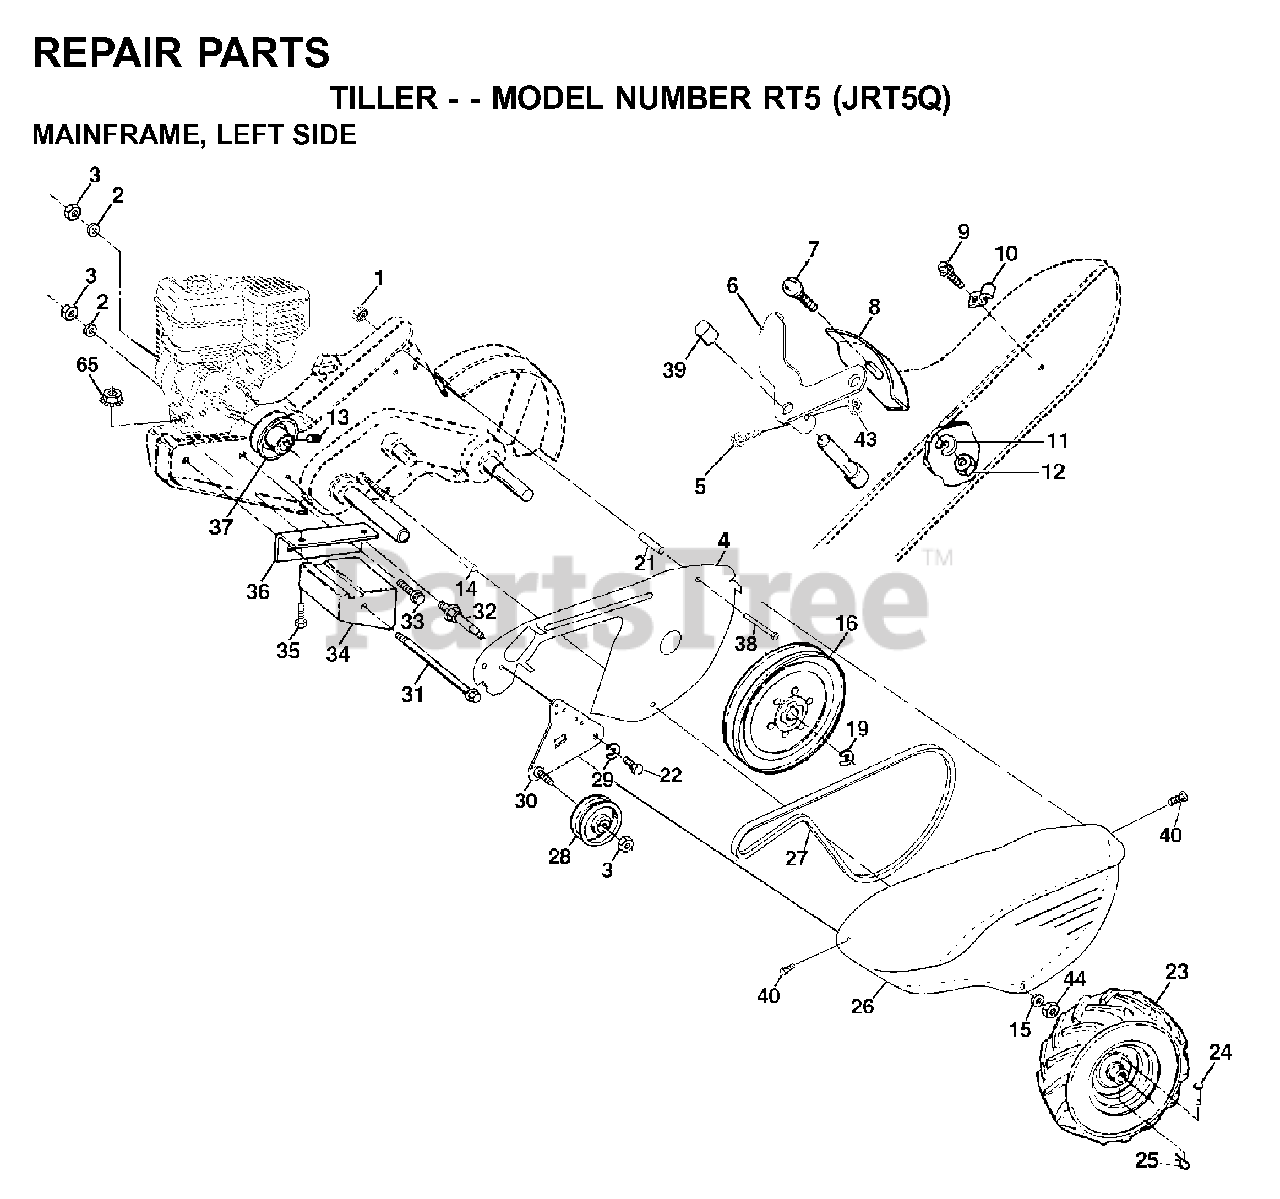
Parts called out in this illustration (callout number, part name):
1	NUT
2	WASHER, LOCK 3/8
3	NUT.HEX.3/8-16UNC
5	SCREW, SHIFT LEVER
6	LEVER ASM CRT
9	TAPPING SCREW
10	CONDUIT CLIP T
11	LOCKWASHER
12	NUT
13	SET SCREW **
14	SPACER-SPLIT.327 X .42
15	WASHER
16	SHEAVE, TRANSMISSION
19	RETAINING RING LT
21	SPACER CRT
24	RIVET,DRILLED
25	RETAINER M
27	V-BELT
28	PULLEY-IDLER TI
29	KLIP RING
30	BRACKET.ASM.IDLER
31	BOLT.FIN.HEX.3/8-16UNC
32	SHIFT ARM CRT
33	BOLT
34	COUNTERWEIGHT.LH.CRT
36	BRACKET LH CRT
37	ENGINE PULLEY
38	BOLT
39	CAP.PLUNGER.BLACK
44	LOCKNUT
65	LOCKNUT-FLANGE 5/16-18
532124366	RIM
532124718	VALVE STEM LT
